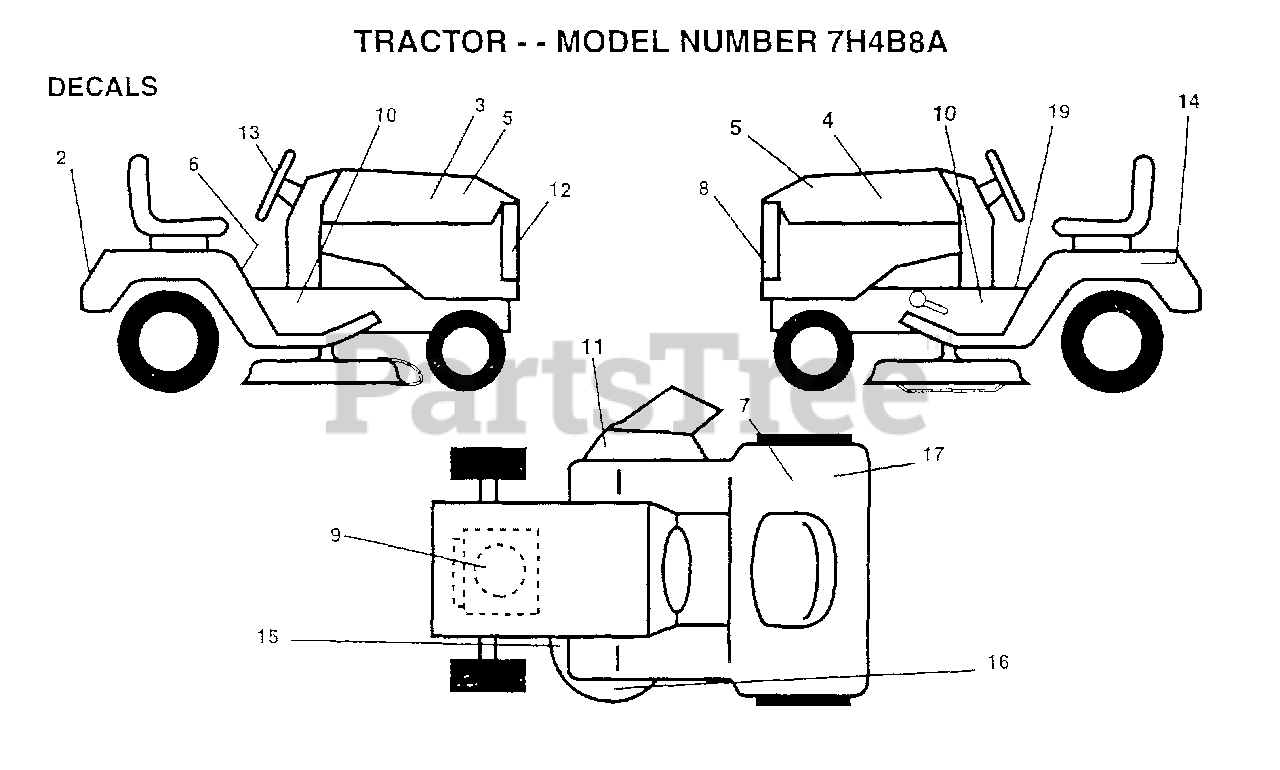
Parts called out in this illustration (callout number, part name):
2	FENDER DECAL
3	DECAL HOOD RH RLY
4	DECAL HOOD LH RLY
6	DECAL.READ.O.MANU
7	DECAL.EURO.ST.CE.
9	DECAL, HP ENGINE
10	"DECAL CHASSIS 42"""
11	DECAL.DANGER.CUTF
12	GRILL DECAL
13	"DECAL,STR WHL"
14	DECAL.BTRY.DANGER
15	DECAL
19	DECAL BRAK PARK
